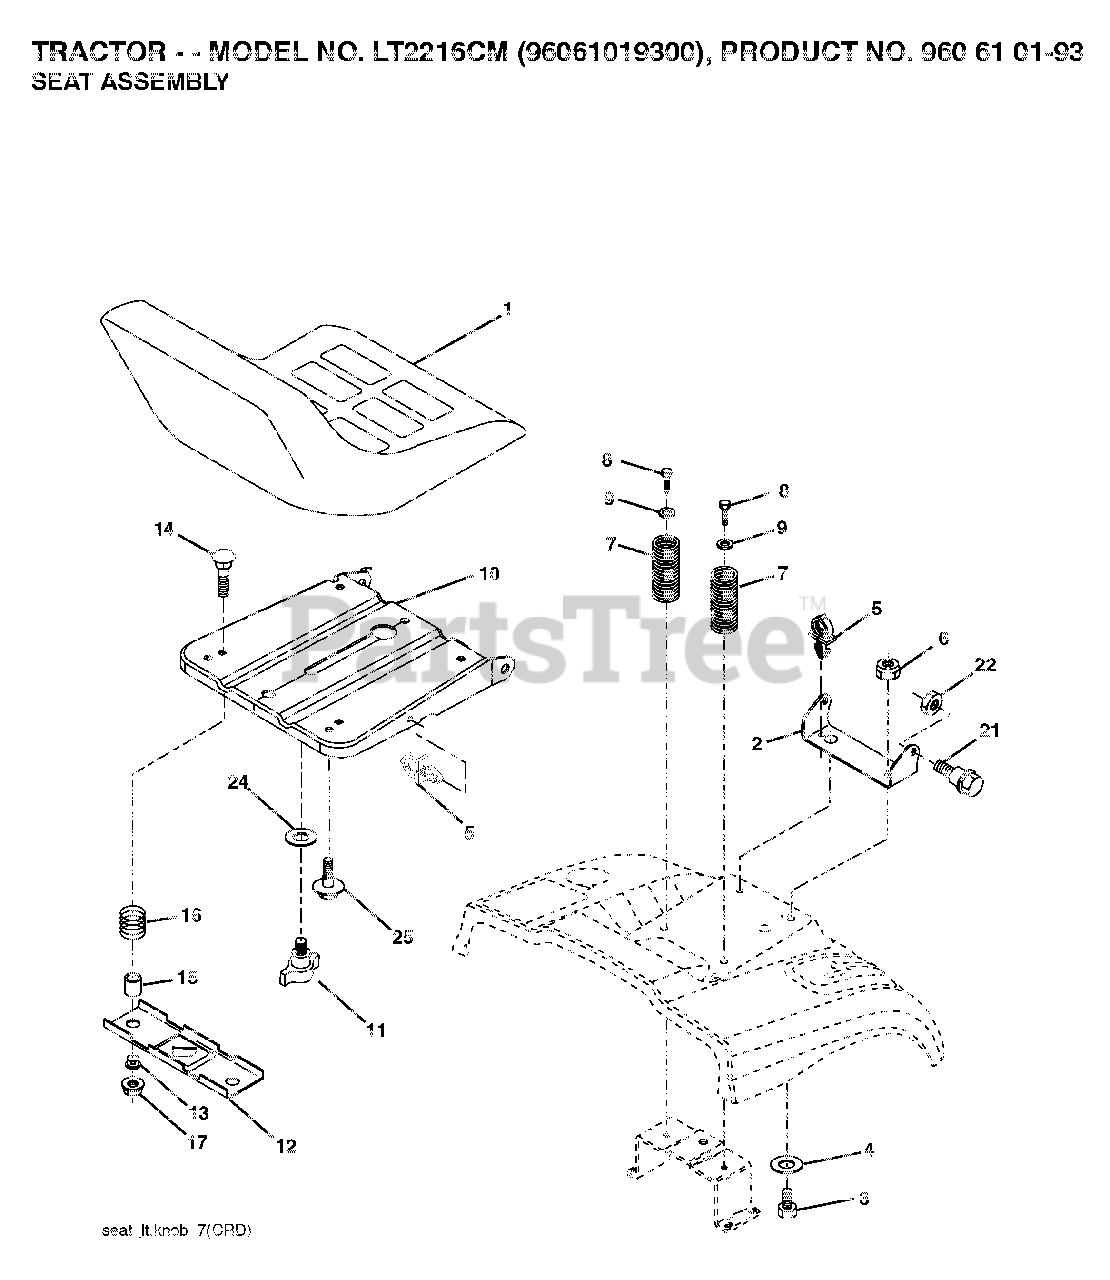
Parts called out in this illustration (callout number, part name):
2	SEAT PIVOT BRKT
4	WASHER PM
5	PUSH CLIP
6	NUT
7	SPRING COMPRESSION
8	SCREW 3/8-16X1
9	WASHER
10	PAN.ASM.SEAT.1SLOT
11	KNOB.SEAT.ADJ.WINGNUT
12	BRKT.MNTNG.SWITCH.SEAT
14	BOLT.ROUND.HEAD.SQUARE.NECK
15	SPACER SPLIT 28X.96
17	NUT T
21	BOLT.SHOULDER.5/16-18
22	NUT.71038.31-18.HEX.NYLOCK
25	BOLT,SHOULD
